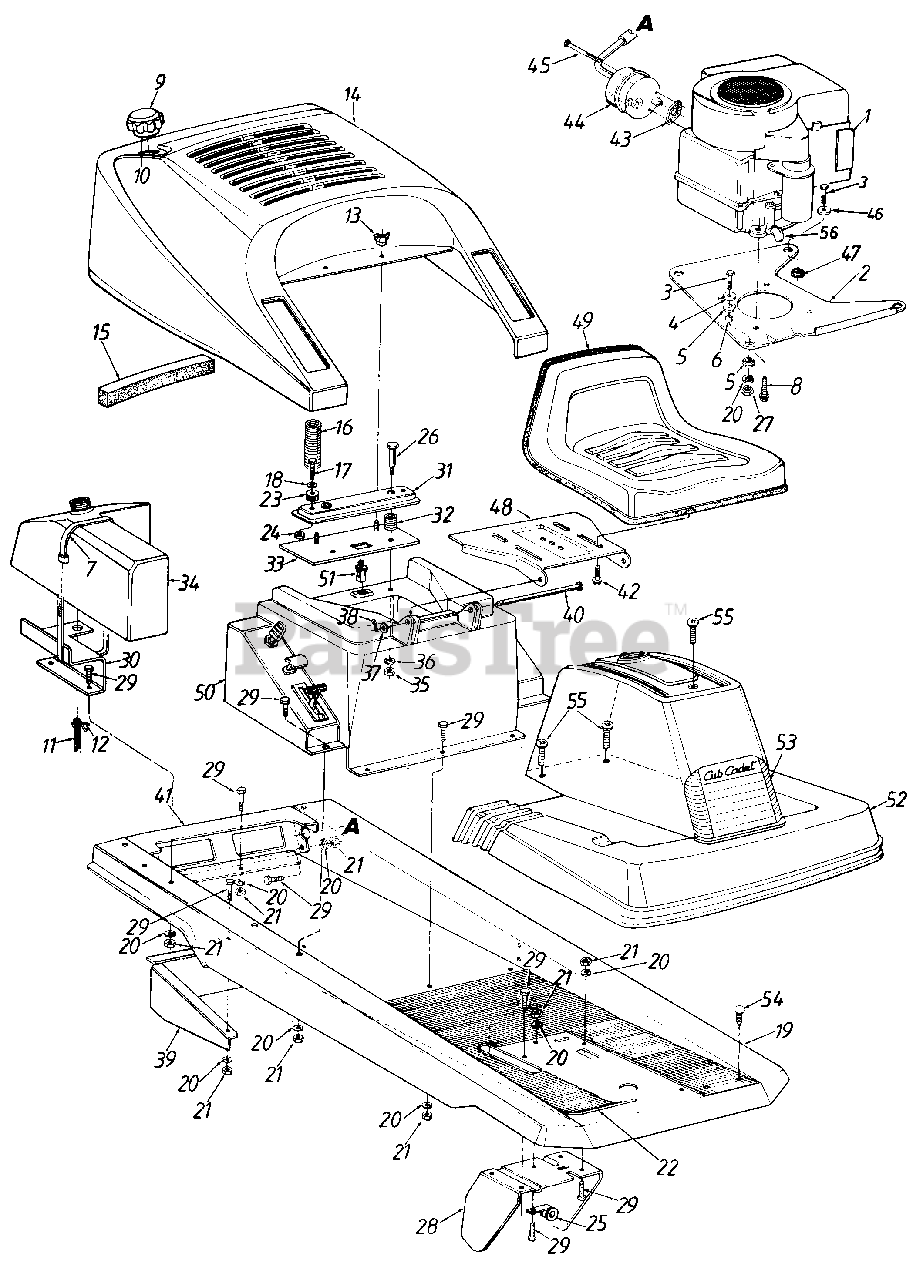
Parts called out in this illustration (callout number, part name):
1	Engine
4	Fl-Wash. .33" I.D. x 1.125" O.D.
5	Engine Mounting Gromme't
6	Spacer .315" I.D. x .5" O.D.
7	Cable Tie 30.6" Lg.
8	Hex Wash. Hd. Self-Tap Scr. 3/8-16 x 1.25" Lg.
9	Gas Cap
10	Gas Cap Gasket
11	Gas Line
12	Hose Clamp
13	Wing Nut w/Washer 1/4-20 Thd.
14	Rear Engine Cover
15	Foam Strip-2 Req'd. (800)
16	Compression Spring 2.34" Lg.
17	Hex Bolt 5/16-18 x 718" Lg. (Gr. 5)
18	Fl-Wash. .344" I.D. x .875"
21	Hex Nut 5/16-18 Thd.
23	Elastemer Bushing
24	Hex Cent. L-Nut 5/16-18 Thd. (Gr. 5)
26	Shld. Bolt .5" Dia. x .84
27	Hex Nut 5/16-24 Thd.
28	Clutch Pedal Brkt. Ass'y.
29	Hex Bolt 5/16-18 x .75" Lg.
35	Hex Nut 3/8-16 Thd.
36	L-Wash. 3/8" I.D.
37	Fl-Wash. .469" I.D. x .88" O.D.
38	Cotter Pin 1/8" Dia. x 1.0" Lg.
43	Exhaust Gasket (800)
44	Muffler (800)
45	Shld. Bolt 3/8" Dia. x 3-5/8" (800)
46	Fl-Wash. .33" I.D. x 1.125" O.D.
47	Flange Washer .32" I.D. x .5"
48	Seat Pivot Bracket
49	Seat Ass'y.
50	Seat Support
51	Safety Switch (Seat)
52	Front Console
53	Headlight Lens
54	Ratchet Fastener .25" Dia. x .75" Lg.
55	Pan Hd. Tap Scr. #12 x .5" Lg.
56	90ø Elbow Male to Female
